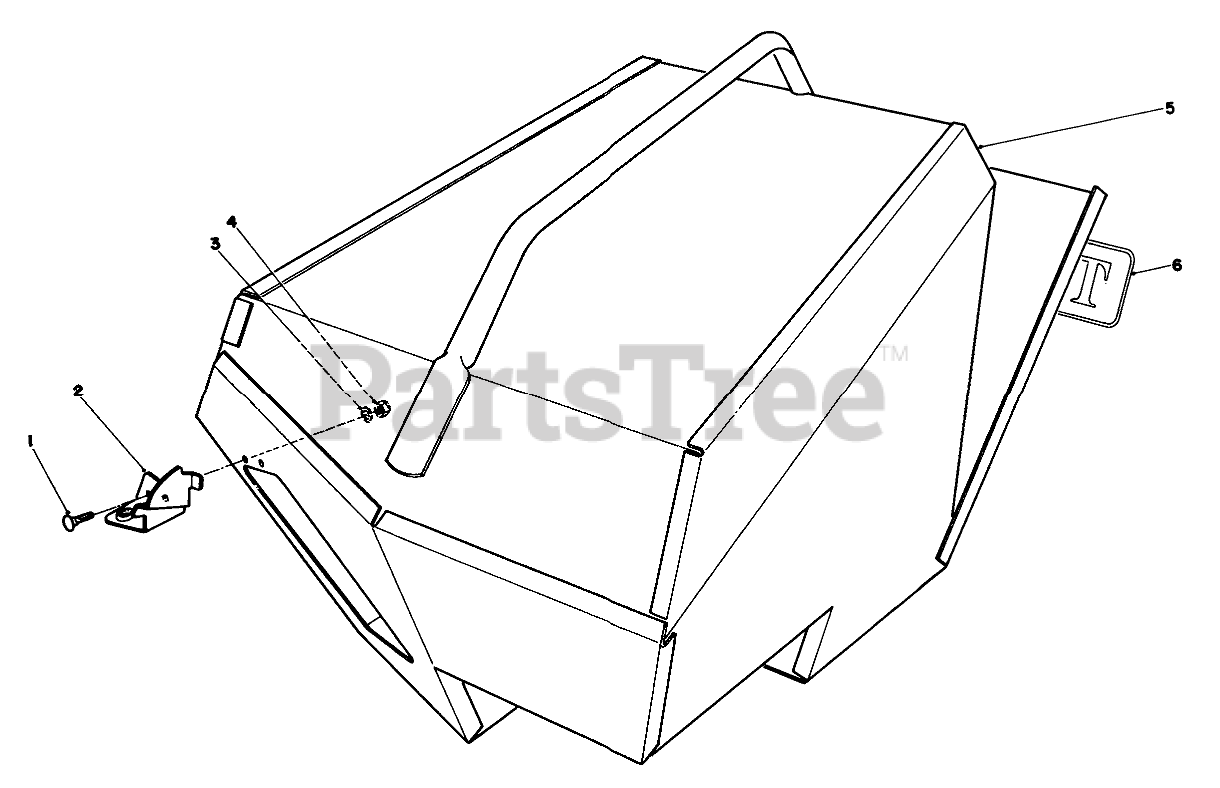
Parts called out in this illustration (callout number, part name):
1	SCREW-CARR
2	Bracket-Latch
3	WASHER-FLAT
4	NUT-LOCK, NI
5	Bag-Steel
6	Decal
